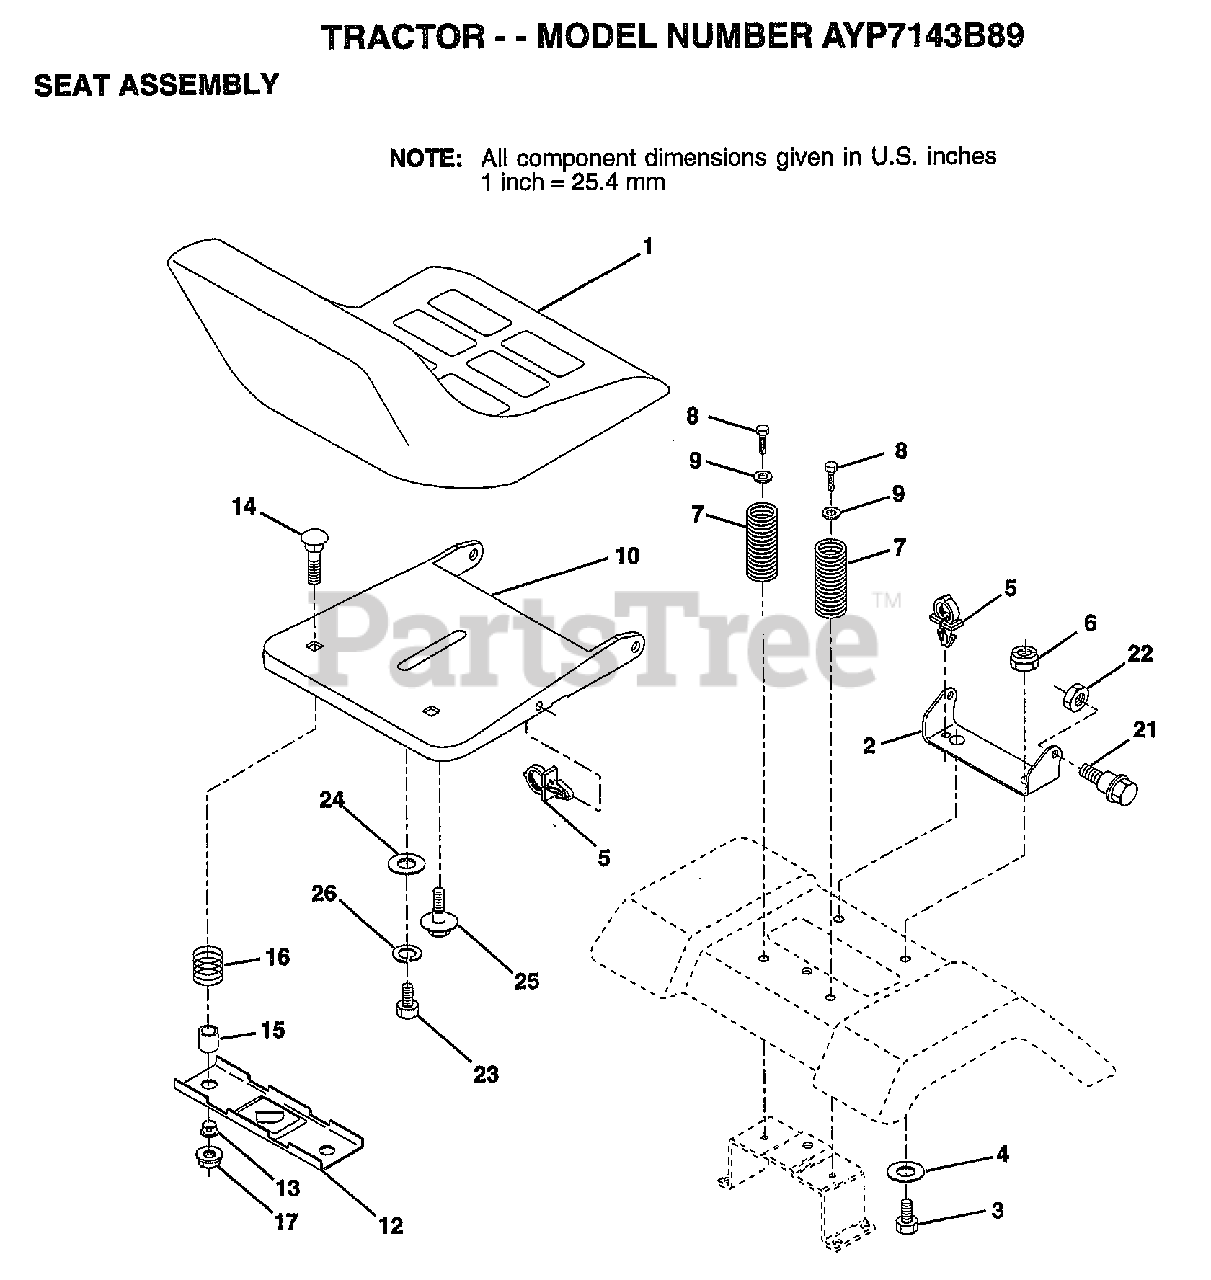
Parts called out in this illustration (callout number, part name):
2	BRACKET PVT SEAT
3	BOLT
4	WASHER PM
5	CLIP.PUSH-IN.HING
6	NUT
7	SPRING COMPRESSIO
8	SCREW GTV
9	WASHER
10	PAN-SEAT
12	BRKT SWITCH
13	BUSHING
14	BOLT-RD HD SQ NK
15	SPLIT SPACER
21	"BOLT,SHOULDER"
22	NUT
23	BOLT
24	WASHER
25	"BOLT,SHOULDER"
26	LOCKWASHER
